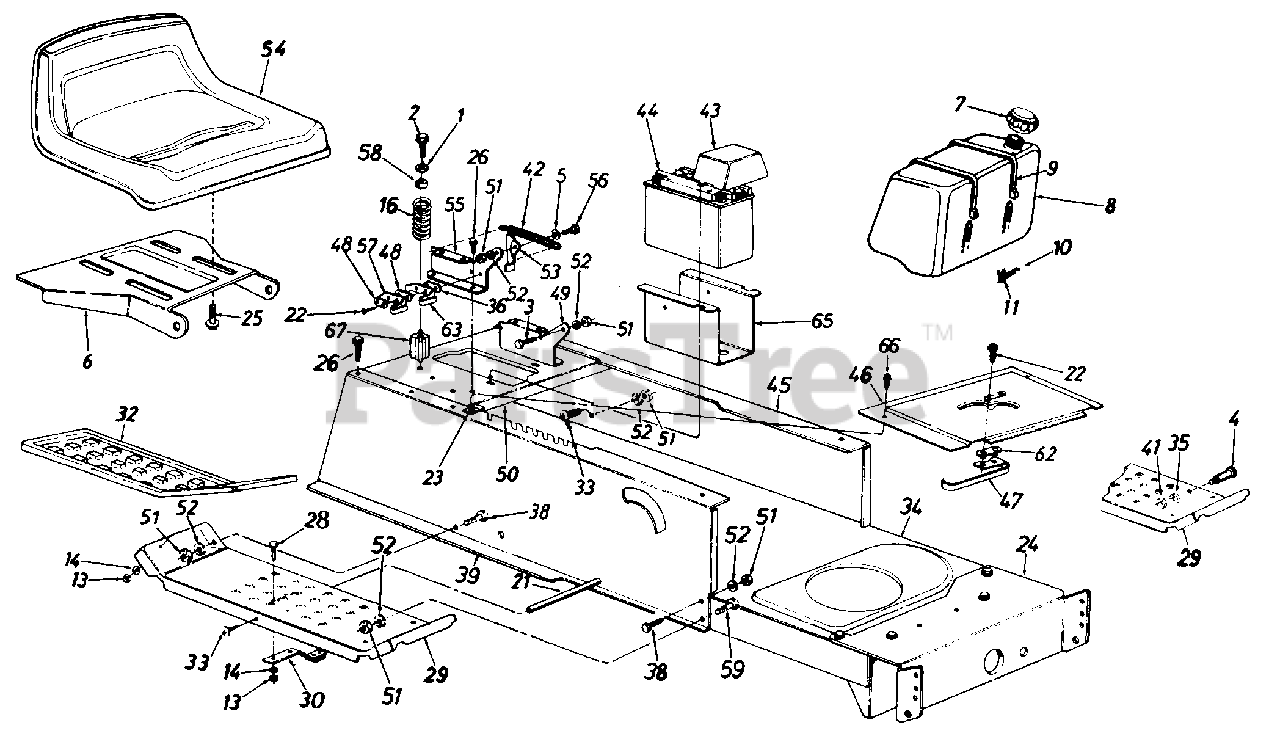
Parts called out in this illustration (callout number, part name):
1	Fl-Wash. .344" I.D. x .875"
2	Hex Wash. Hd. Tap Scr. 5/16-18 x 3.25" Lg.
3	Shld. Bolt .437" Dia. x .162"
4	Shld. Bolt .50" Dia. x .84"
5	Spr-Wash. .445" I.D. x .75
6	Seat Pivot Bracket
7	Fuel Cap
8	Fuel Tank
9	Tie Strap
10	Fuel Line
13	Hex Nut 1/4-20 Thd.
14	L-Wash. 1/4" I.D.
16	Compression Spring
21	Running Board Rod
22	Hex Wash. Hd. AB-Tap Scr. #8 x .50" Lg.
23	Speed Nut #10Z
24	Front Pivot Brkt.
25	Hex Tap Scr. 3/8-16 x .75"
26	Hex Wash. Hd. AB-Tap Scr. 5/16 x .75" Lg.
28	Carriage Bolt 1/4-20 x .62"
29	Running Board
30	Blade Brake Ass'y.
32	Rubber Foot Pad-L.H.
33	Truss Mach. Scr. 5/16-18 x .75" Lg.
34	Lower Frame
35	L-Wash. 3/8" I.D.
36	Insulator Boss Plate
38	Hex Bolt 5/16-18 x .75n Lg.
39	483/N Upper Frame-R.H.
41	Hex Nut 3/8-16 Thd.
42	Extension Spring 5.31" Lg.
43	Battery Cover
44	12-V Battery (275 Cold Crank Amps)
45	Upper Frame-L.H.
46	Shift Cover
47	Reverse Safety Switch
48	Insulator Plate
52	L-Wash. 5/16" I.D.
53	Seat Lift Brkt.
56	Shld. Bolt .437" Dia. x .268"
57	Spring Switch
59	Hex Wash. TT-Tap Scr. 5/16-18 x 7/8" Lg.
62	Insulator Nut Plate
63	Safety Switch
65	Battery Tray
66	Truss Mach. B-Tap Scr. #10 x .5" Lg.
67	Spring Spacer
